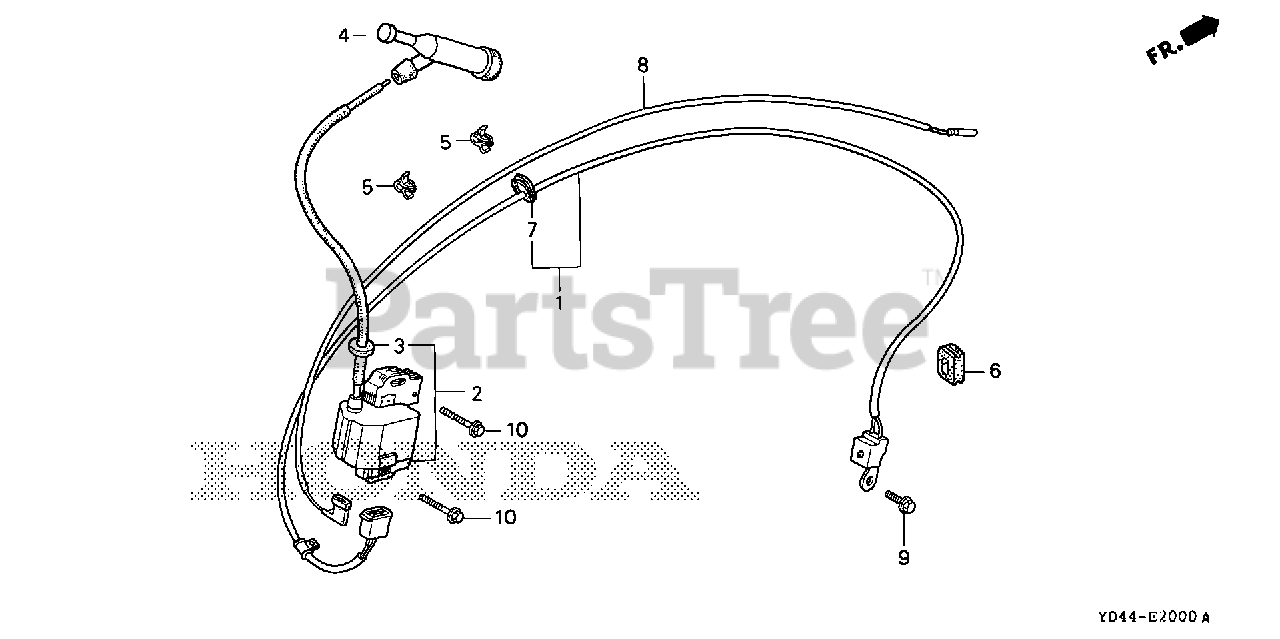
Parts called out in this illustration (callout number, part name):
2	COIL ASSY., IGNITION
4	CAP ASSY., NOISE SUPPRESSOR (NICHIWA Y-EZ RTFM256)
5	CLIP, IGNITION WIRE (8MM)
6	GROMMET, WIRE
8	WIRE, STOP SWITCH (430MM)
10	BOLT, FLANGE (6X28) (CT200)
